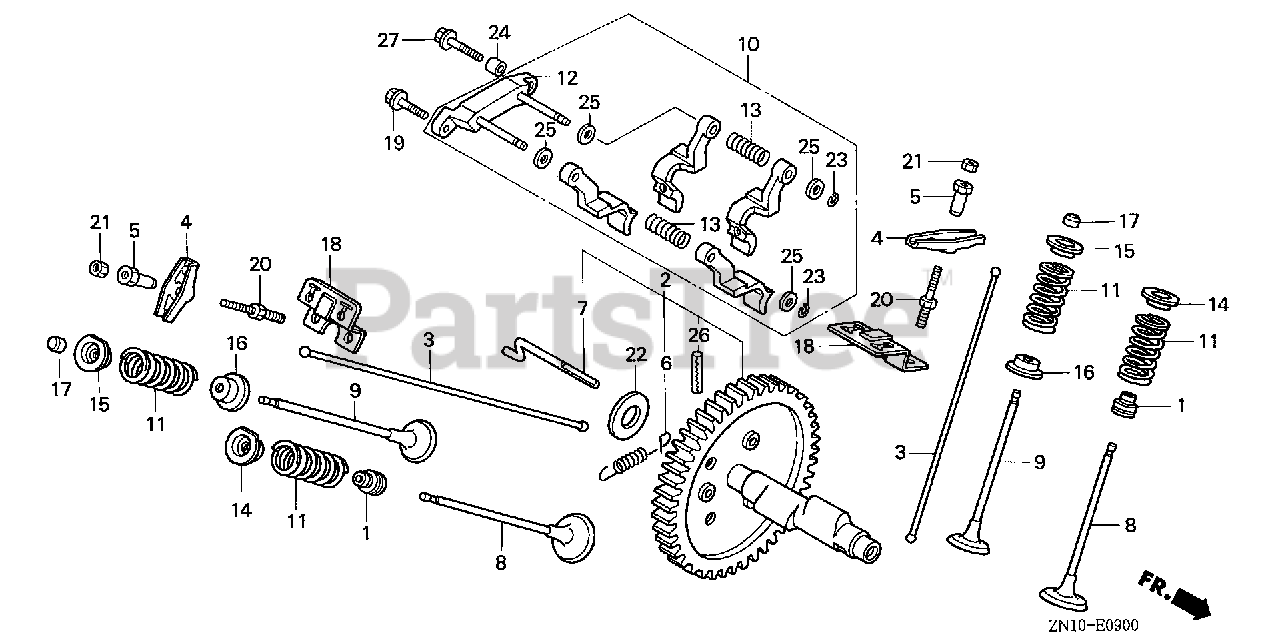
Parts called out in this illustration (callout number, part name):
1	SEAL, VALVE STEM
2	CAMSHAFT ASSY.
4	ARM, VALVE ROCKER
5	PIVOT, ROCKER ARM
6	SPRING, WEIGHT RETURN
7	PIN, DECOMPRESSION
8	VALVE, IN.
9	VALVE, EX.
10	LIFTER ASSY., VALVE
11	SPRING, VALVE
12	SHAFT, VALVE LIFTER
13	SPRING, VALVE LIFTER
14	RETAINER, IN. VALVE SPRING
15	RETAINER, EX. VALVE SPRING
16	SEAT, VALVE SPRING
17	ROTATOR, VALVE
18	GUIDE, PUSH ROD
19	BOLT, FLANGE (5X16)
20	BOLT, PIVOT (8MM)
21	NUT, PIVOT ADJUSTING
22	WASHER, THRUST (17.2MM)
23	CLIP, GOVERNOR HOLDER
24	PIN A, DOWEL (8X12)
25	WASHER, PLAIN (6MM)
26	PIN, SPRING (6X28)
27	BOLT, FLANGE (6X25)
